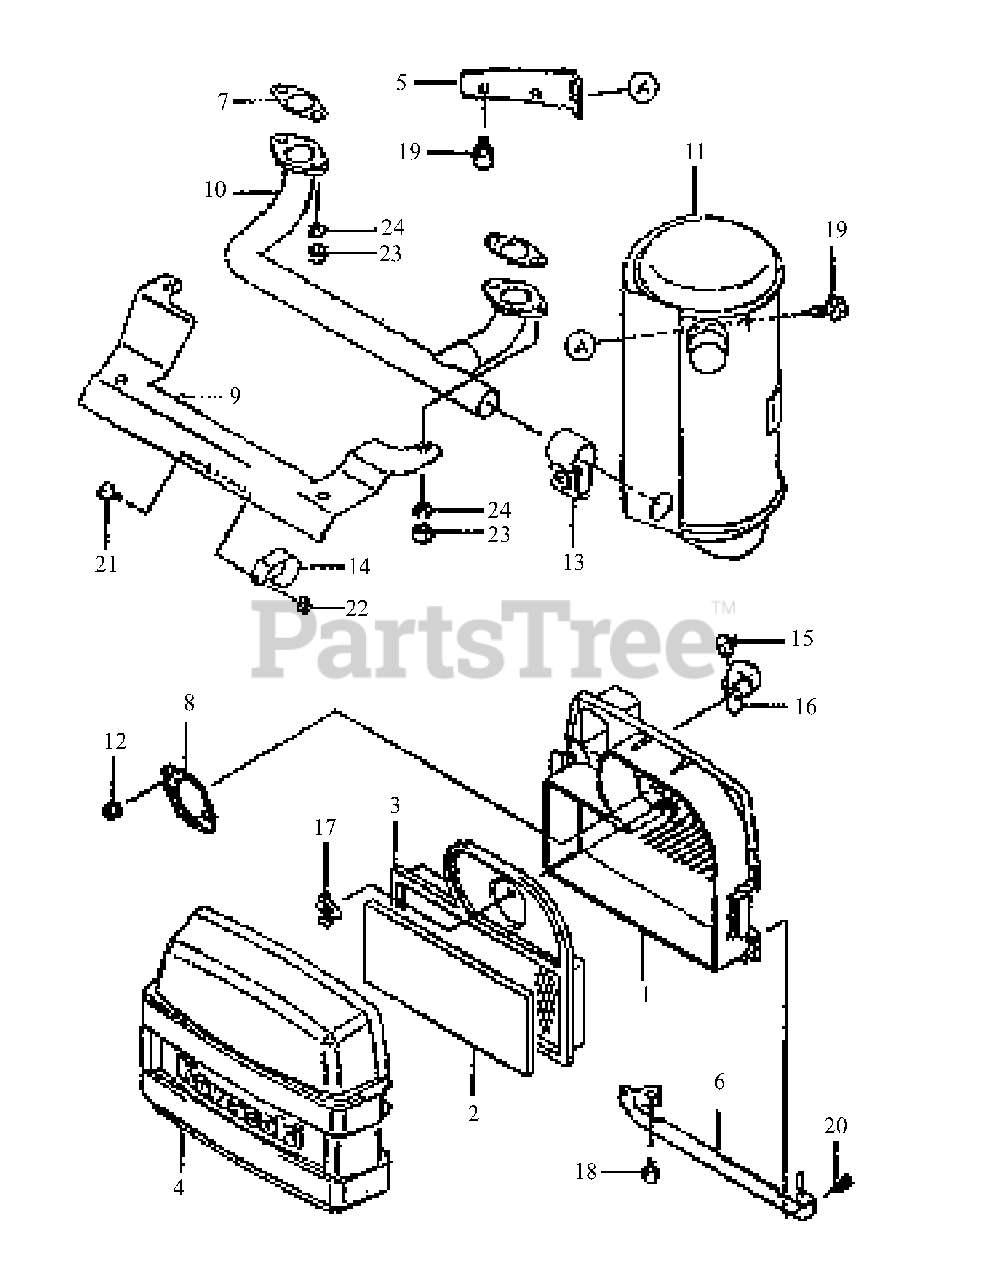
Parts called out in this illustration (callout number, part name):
1	Case, Air Filter
2	Element, Pre Cleaner
3	Element, Air Filter
4	Case, Air Filter
7	Gasket, Muffler
10	Pipe, Exhaust
18	Bolt, Flange
19	Bolt, Flange
20	Screw
24	Washer, Spring
